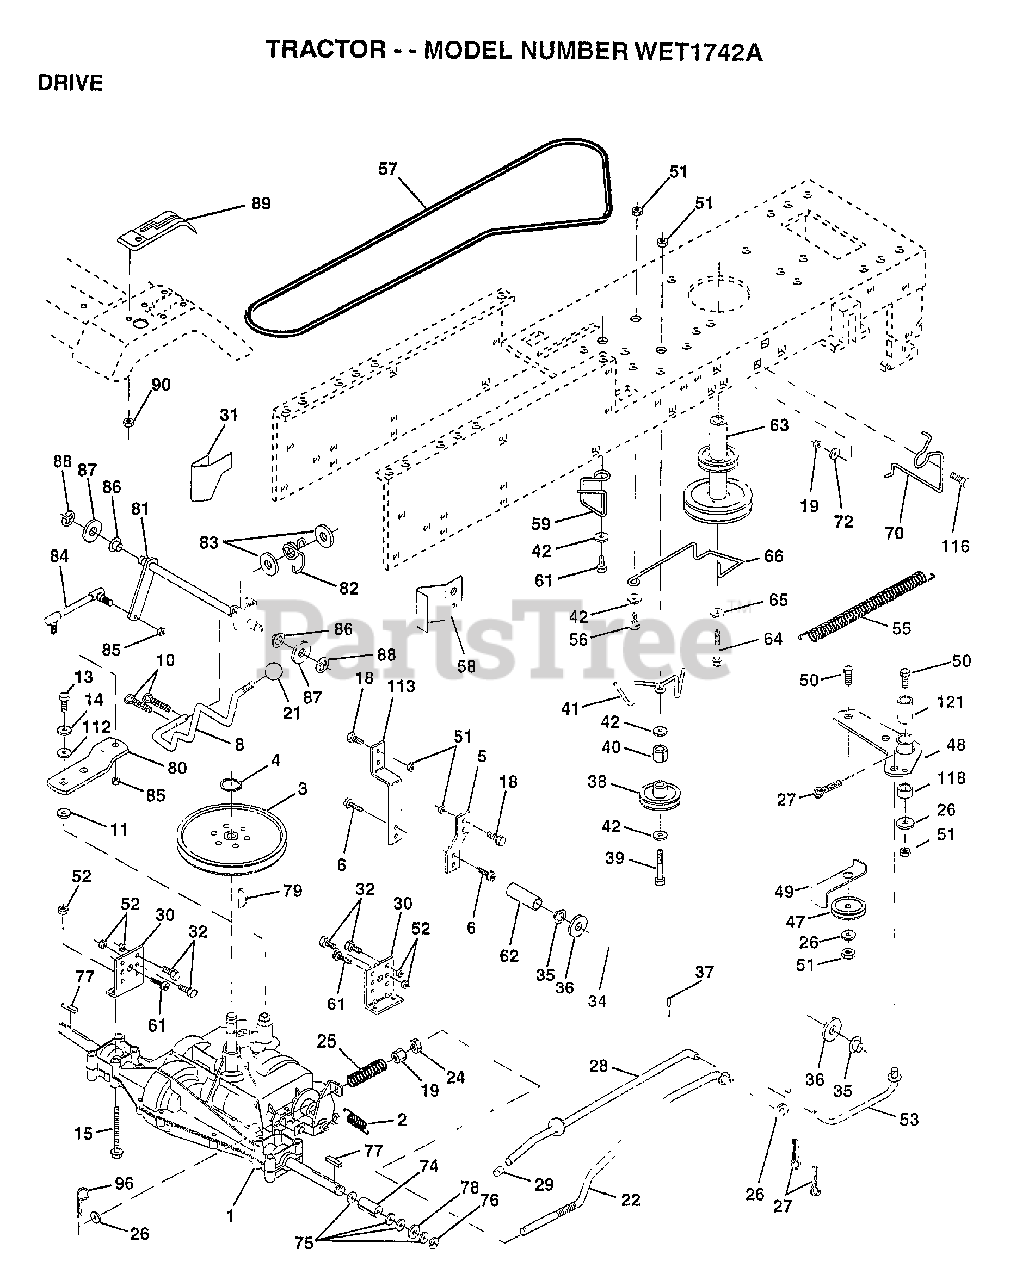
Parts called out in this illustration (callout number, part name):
1	TRANSAXLE, PEERLESS
2	SPRING.BRAKE.RETU
3	PULLEY TRANS
5	SPRING
6	SCREW
8	ROD SHIFT FEND LT
10	PIN COTTER 1/8
11	WASH-SHFT PLT LT
13	BOLT.1/4-28.W/PAT
14	LOCKWASHER
15	BOLT.HX.FLG.5/16
18	BOLT
19	NUT
21	KNOB T (1/2-HOLE)
22	BRAKE ROD
24	NUT
25	SPRING ROD LT
26	WASHER
27	COTTER PIN
28	ROD.BRAKE.PARK.LT
29	PLUNGER CAP T
30	TRANSAXLE MTG BKT
31	"KEEPER,BELT LH T"
32	BOLT
34	SHAFT ASM-PEDAL F
35	NYLON BEARING
36	WASHER LT
38	PULLEY.IDLER.FLAT
39	BOLT
40	SPACER T
42	WASHER
48	BELLCRANK ASM
49	RETAIN BELT
52	NUT
53	"LINK, CLUTCH T"
55	"SPRING, RETURN LT"
58	"KEEPER,BELT RH T"
59	KEEPER BELT CNTSP
61	SCREW
62	PEDAL COVER T
63	PULLEY.ENGINE
64	BOLT
65	LOCKWASHER
66	KEEPER-BELT
70	KEEPER BELT ENG
72	WASHER
74	SPACER AXLE
75	WASHER
76	E-RING LT
77	SQUARE KEY
78	WASHER
80	"ARM.SHIFT.20""TIRE"
81	SHAFT.CROS.P930.
82	"SPRING,TORSION"
83	WASHER
84	"ROD.TIE.20""P930LT"
85	NUT.CNT.LOCK.1/4
86	BUSHING
87	WASHER D
88	KLIP RING
90	NUT
96	RETAINER M
112	WASHER LT
113	"STRAP,TORQUE"
116	BOLT RDHD 3/8-16
118	SPACER-BELLCRANK
121	NYLINER-CLUTCHING
